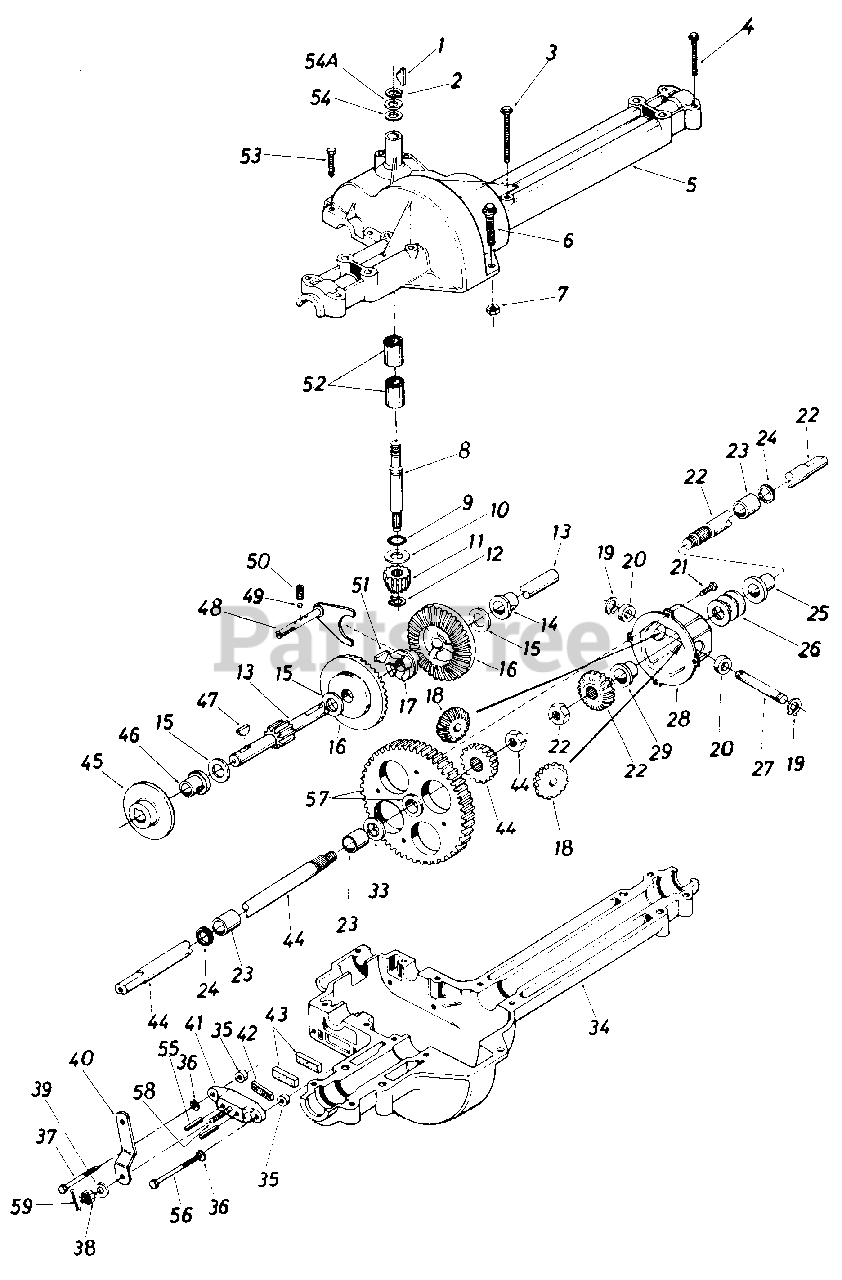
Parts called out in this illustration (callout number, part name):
1	#4 Hi-Pro Key 3132 x S18n Dia.
2	Snap Ring .625" Shatt
3	Hex Bolt 1/4-20 x 1.75" Lg.
4	Hex Bolt 5/16-18 x 2.5"
5	Upper Housing
6	Hex Fl-Bolt 1/4-20 x .88" Lg.
7	Hex Nut 1/4-20 Thd.
8	Input Shatt
9	Square Seal 5/8" l.D.
10	Thrust Washer 5/8" I.D. x 1.25" 0 D
11	Pinion Input 14T
12	Retaining Ring 7/16" Ext.
14	Flange Brg. 5/8" l.D. x 3/4" Lg.
15	Fl-Wash.
16	Bevel Gear 42T
17	Clutch Collar
18	Miter Gear 15T (H.D.)
19	Snap Ring
20	Thrust Bearing l/zn l.D. x l.on O.D.
21	Pan Head Scr. 1/4-20 x .50" Lg. wlPatch
22	Axle R.H. Ass'y.-Kit
23	Sleeve Bearing 3/4" l.D. x 1.0 Lg.
24	Oil Seal 3/4" l.D.
25	Flange Bearing 3/4" I.D. x 1 5116n Lg.
26	Fl-Wash. .760" l.D. x 1.49n O.D.
27	Cross Shatt
28	Differential Housing Ass'y.
33	Fl-Wash. .760" l.D. x l.49" O.D.
34	Lower Housing
35	Spacer 53" O.D. x 3/8" Lg.
36	L-Wash. l/4" l.D.
37	Hex Bolt 1/4-20 x l.50" Lg. (Grade 5)
38	Castle Nut 5/16-24 Thd.
39	Fl-Wash. 344" l.D. x 375" O.D.
40	Actuating Arm
42	Puck Plate
43	Brake Puck
44	Axle L.H. Ass'y.-Kit
46	Flange Bearing 5/8" l.D. x 15/16" Lg.
47	Woodruff Key 3/16 x 5/8 HT
48	Shift Fork Ass'y.
49	Ball Detent .250" Dia.
50	Spring Detent
51	#9 Hi-Pro Key 3/16 x 3/4 0 Dia. HT
52	Needle Brg. 5/8" l.D. x 1/2" Lg.
53	Hex Bolt 1/4-20 x 1.00" Lg
54	Fl-Wash. 5/8" l.D. x .030
54A	Fl-Wash. 5/8" l.D. x .040
55	Actuating Pin 5/16" Dia.
56	Hex Bolt 1/4-20 x 2.50" Lg. (Grade 5)
57	Differential Gear 72T Ass'y. w/Bearing
58	Sq. Hd. Bolt 5/16-24 Thd.
59	Cotter Pin 3/32" Dia. x .50n Lg.
